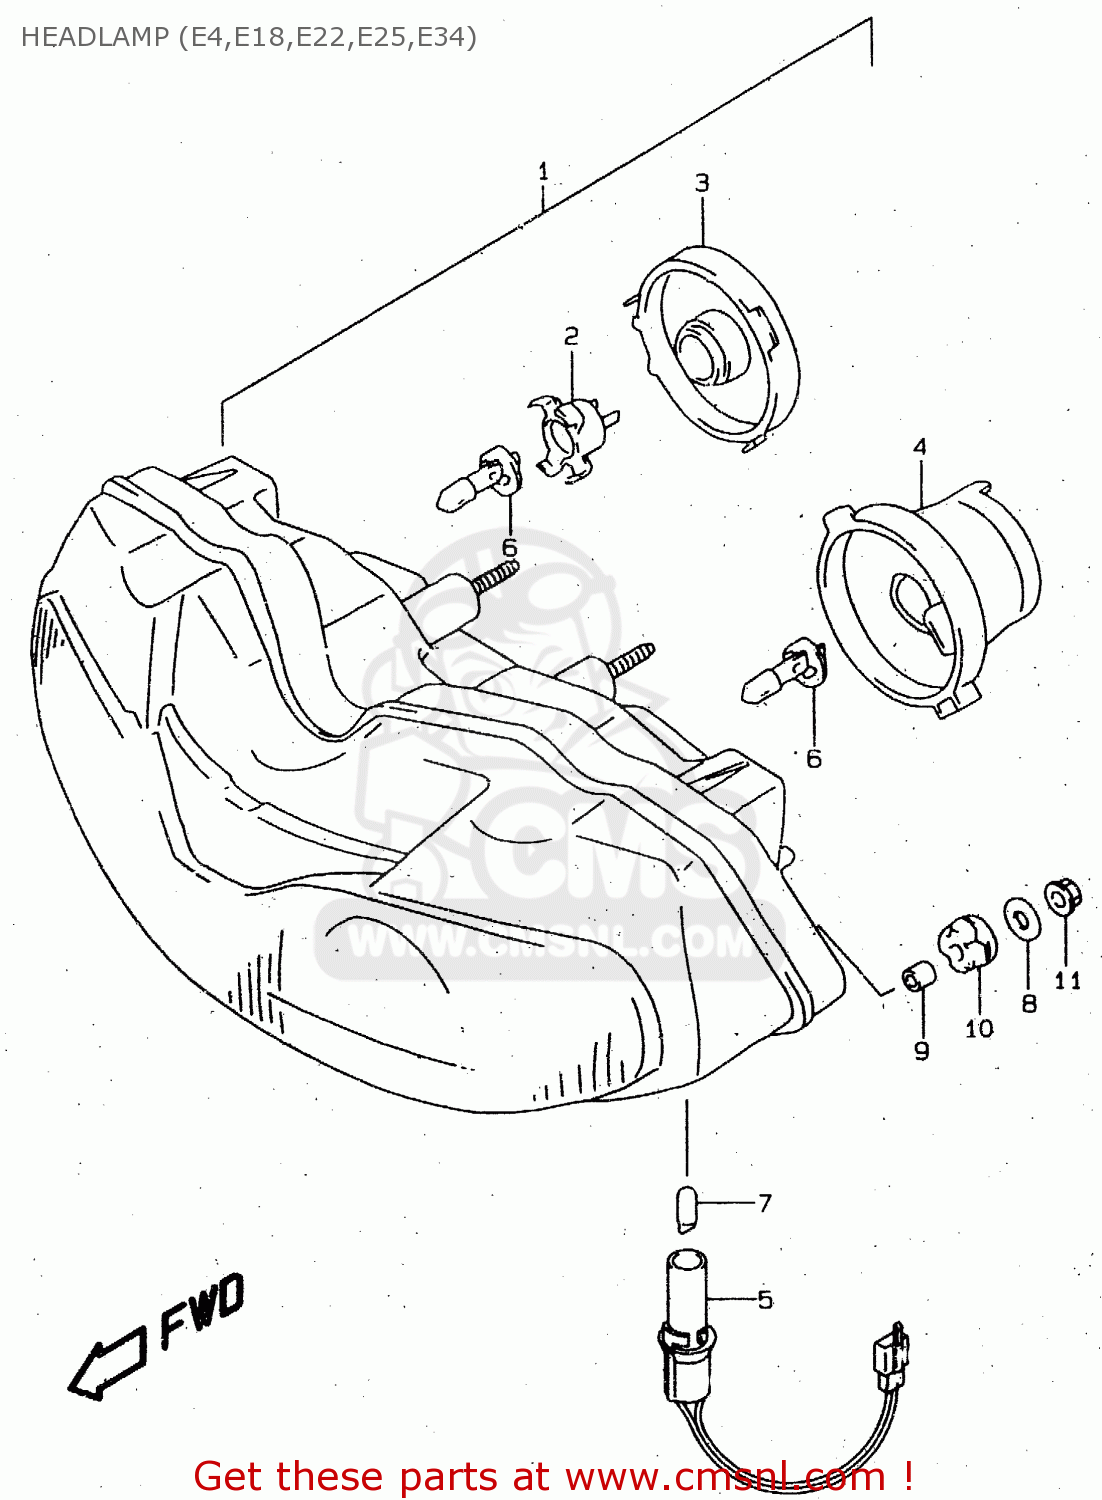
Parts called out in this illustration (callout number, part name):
1	HEADLAMP ASSY
2	ADAPTER ASSY
3	COVER,SOCKET
4	SOCKET & CORD ASSY
5	SOCKET ASSY
6	BULB(12V55W/H1/P14.5S/OSRA,PHI
7	BULB(12V5W)
8	WASHER(6.5X20X1.6)
9	SPACER(6.5X9X13.5)
10	CUSHION
11	NUT
